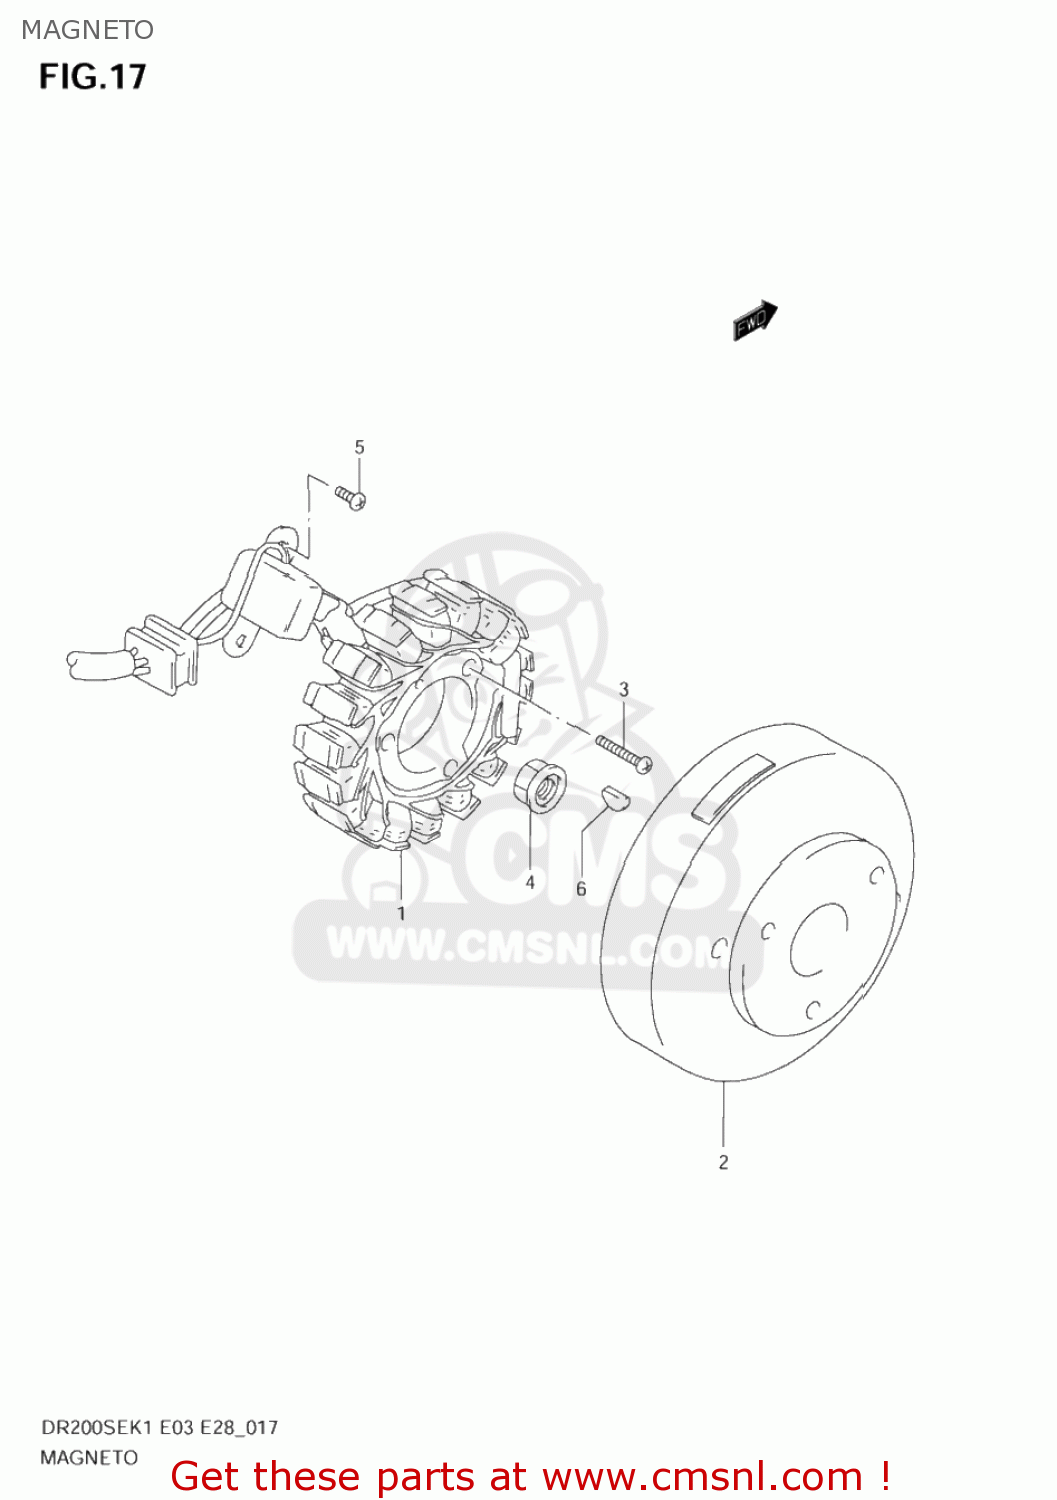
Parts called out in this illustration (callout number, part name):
1	STATOR ASSEMBLY
2	ROTOR ASSY
3	SCREW
4	NUT
5	SCREW
6	KEY
